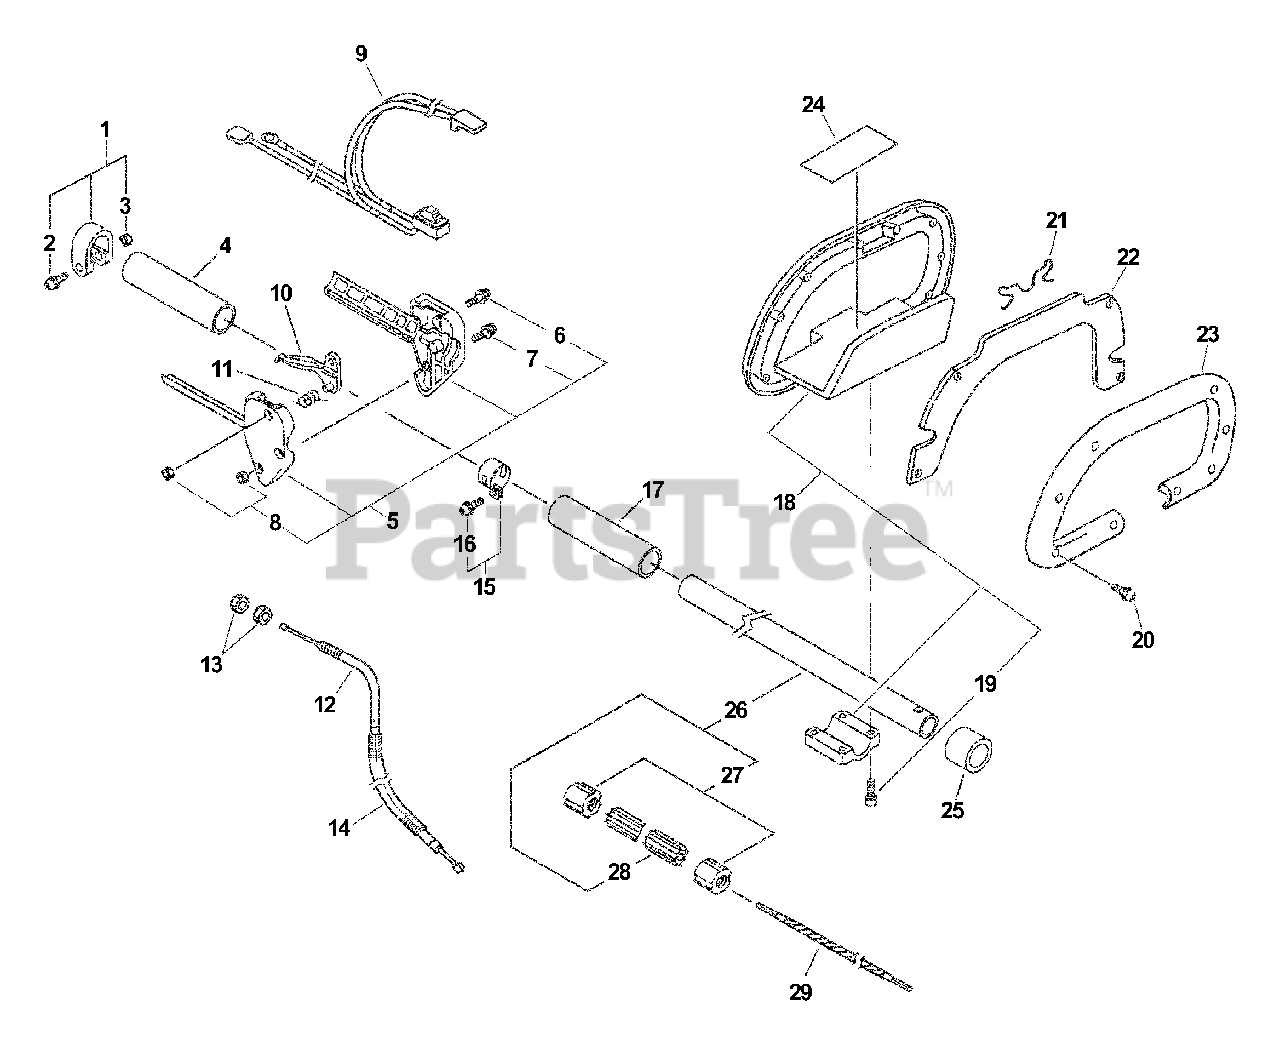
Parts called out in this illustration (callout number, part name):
1	CLAMP
2	SCREW - 5X28
4	GRIP, HANDLE - REAR
5	CONTROL HANDLE ASSY
6	SCREW - 5X35
7	SCREW - 5X25
9	IGNITION SWITCH ASSY
10	TRIGGER, THROTTLE
11	SPRING, TRIGGER
12	CABLE, THROTTLE
14	TUBE, PROTECTIVE - CORRUGATED
15	CLAMP KIT
16	SCREW - 5X14
17	CUSHION
18	HANDLE ASSY - FRONT
19	SCREW - 5
23	COVER, HANDLE
24	LABEL - CAUTION
25	COLLAR
26	MAIN PIPE ASSY
28	LINER - FLEXIBLE
29	DRIVESHAFT - FLEXIBLE
